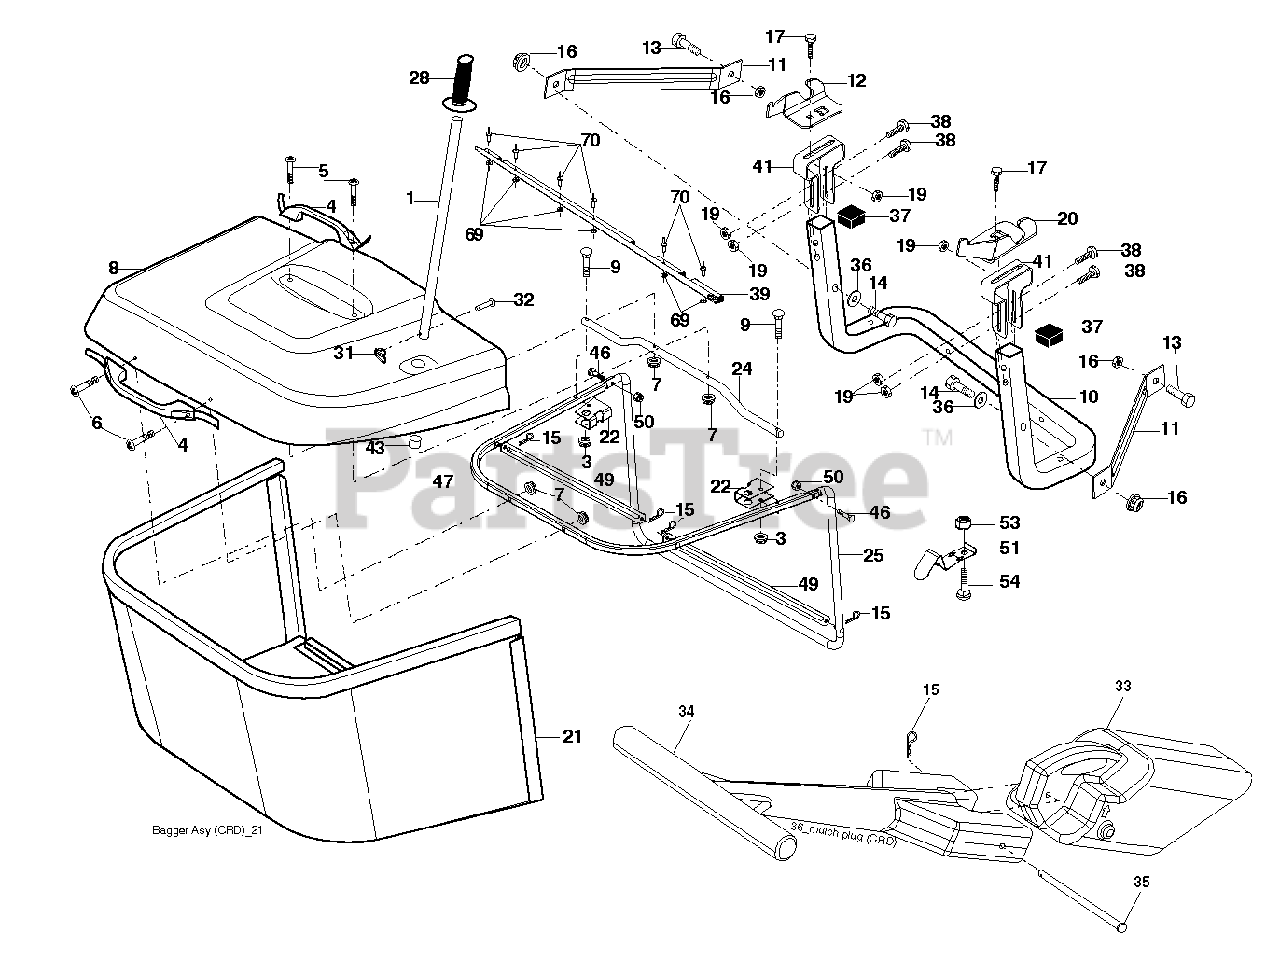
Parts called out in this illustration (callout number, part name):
1	TUBE.PNT.HDL.BAGGER.
3	NUT T
5	SCREW.PAN.HEAD
8	COVER.PNT.BGR.CRD.WSLOTS.MS667
11	BRACKET
14	BOLT-HEX EAK
15	RETAINER-SPRNG RB
16	NUT LOCK FLG 3/8-16 UNC
17	BOLT
19	NUT LOCK HEX FLANGE 5/16-18
20	BRKT.PIVOT.RH.CRD
21	BAGGER.ASM.CRD.2007
22	BRACKET.BAGGER.SD.
24	TUBE
28	GRIP.HANDLE.BLACK
31	RETAINER CLIP
32	RIVET,DRILLED
33	MULCHING.PLUG.1078.CRD.NON-TEX
35	PIN
38	BOLT.5/16-18X2.5
39	SEAL.BAGGER.CRD
41	BRACKET.BAGGER.SD.
43	PLUG, TUBING END
46	BOLT.CARRIAGE.5/16-18
50	NUT.71038.31-18.HEX.NYLOCK
53	NUT
54	BOLT
